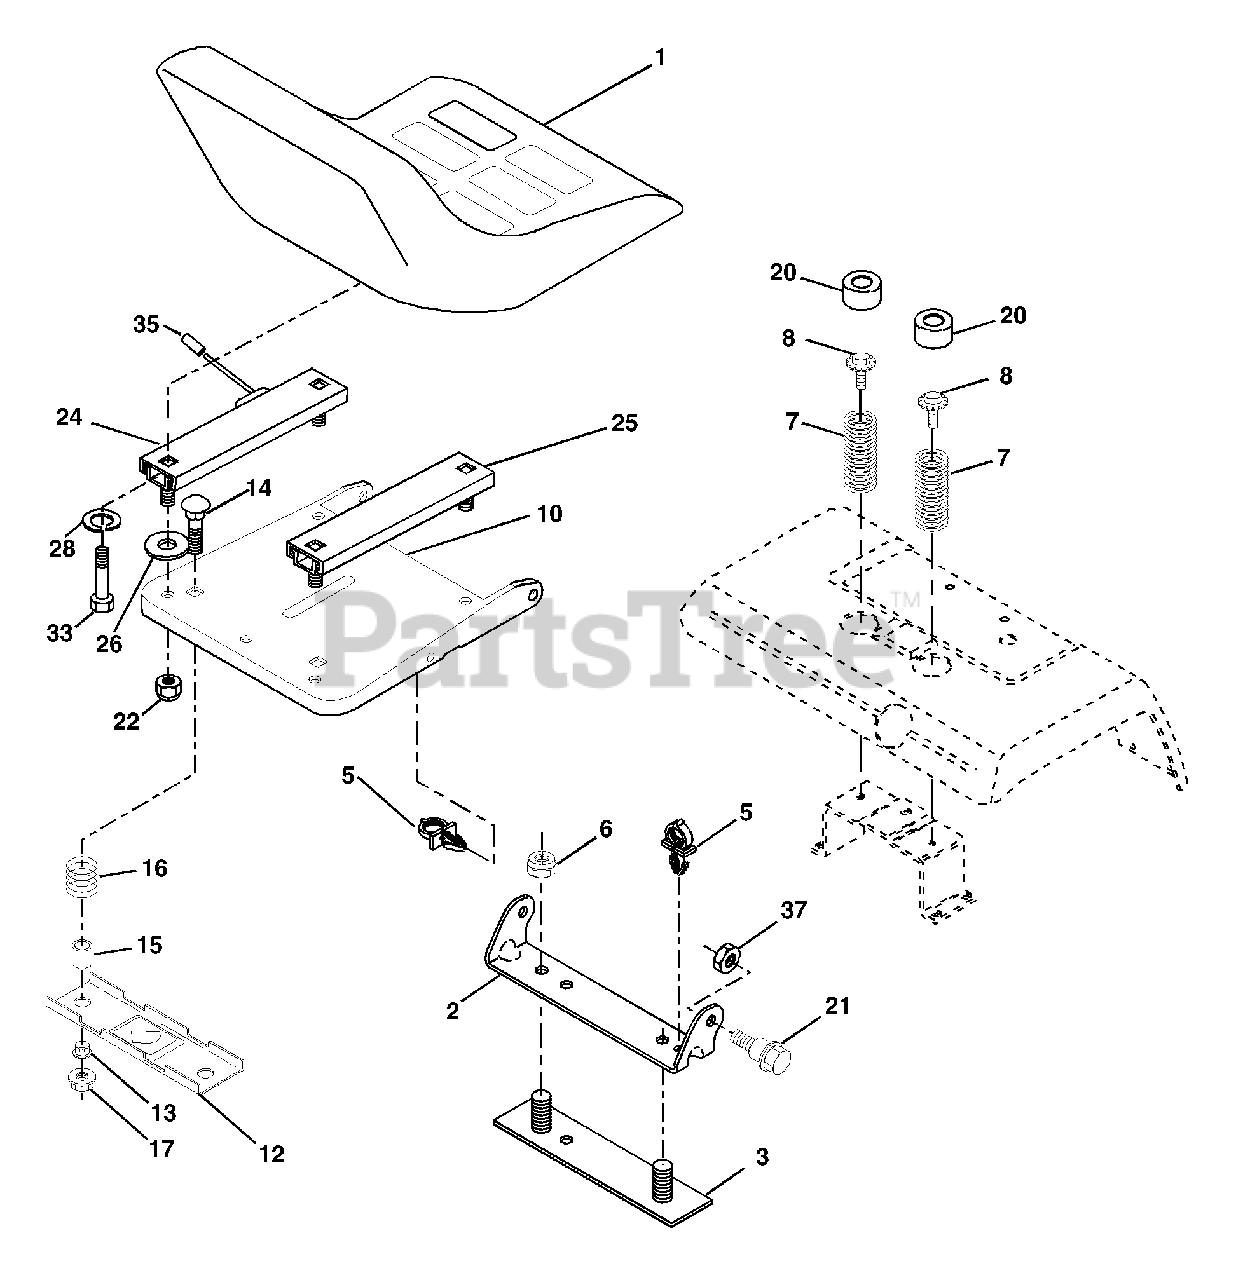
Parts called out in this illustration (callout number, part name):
1	Seat
2	Bracket, Pivot Seat
3	Strap Asm Fender
5	Clip, Push In Hinged
6	Nut, Crownlock 3/8-16
7	Spring, Seat Cprsn
8	Bolt 5/16-18 Unc x 3/4
10	Pan, Seat
12	Bracket, Mounting Switch
13	Bushing, Snap
14	Bolt, Carriage 1/4-20 x 1-1/2
15	Spacer, Split
16	Spring, Cprsn
17	Nut, Lock 1/4 Lge Flg Gr. 5
20	Cap Spring Seat
21	Bolt, Shoulder 5/16-18
22	Nut Crown Lock 5/16-18
24	Track Slide Seat LH
25	Track Slide Seat RH
26	Washer 11/32 x 5/8 x 12 Ga.
28	Washer Split
33	Bolt Fin Hex 5/16-18 x 3/4
35	Cap Vinyl
37	Nut, Crownlock 5/16-18
